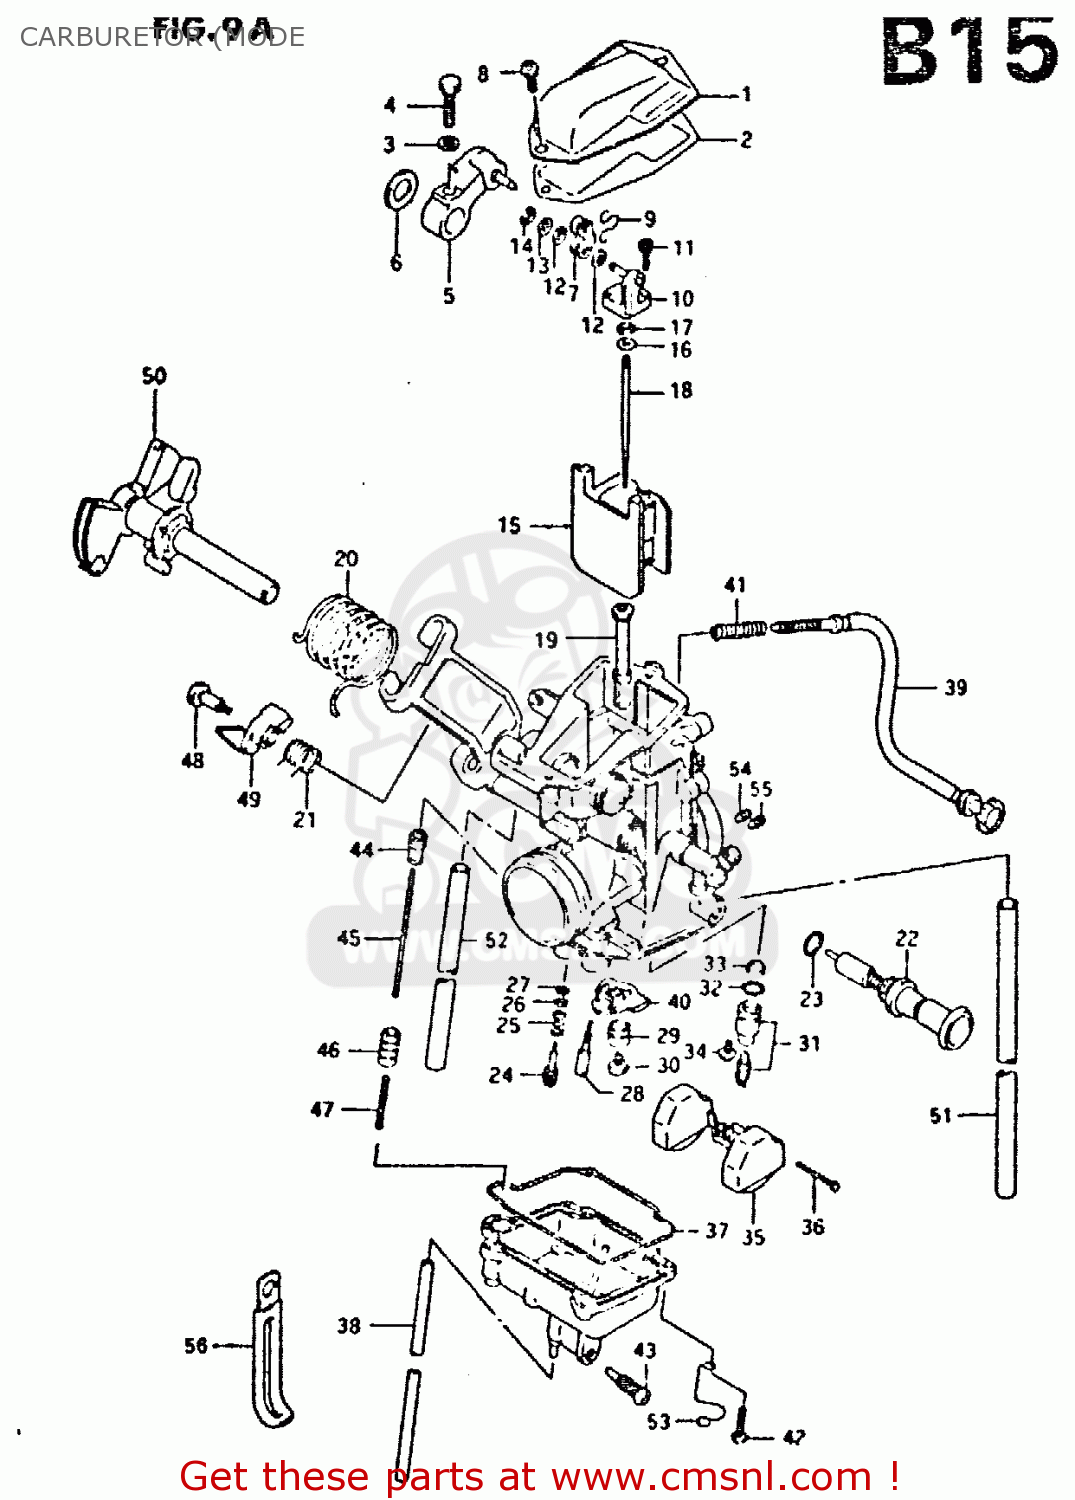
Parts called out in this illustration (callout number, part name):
1	COVER,CARBURETOR,TOP
2	GASKET,CARBURETOR TOP (NAS)
3	LOCK,WASHER
4	BOLT
5	ARM,THROTTLE
6	RING,THROTTLE SHAFT
7	PLATE
8	SCREW
9	SPRING
10	CONNECTOR
11	SCREW
12	GASKET (NAS)
13	WASHER
14	E-RING
15	VALVE,PISTON
16	WASHER,JET NEEDLE
17	CLIP
18	NEEDLE,JET
19	JET,NEEDLE(P-8)
20	SPRING
21	SPRING
22	PLUNGER ASSY
23	O RING
24	SCREW,PILOT
25	SPRING
26	WASHER
27	O RING,PILOT AIR SCREW
28	JET,PILOT(37.5)
29	RING,MAIN JET FIXING
30	JET,MAIN(127.5)
31	VALVE ASSY, NEEDLE
32	O-RING,NEEDLE VALVE
33	FILTER
34	SCREW
35	FLOAT
36	PIN,FLOAT
37	O RING,FLOAT CHAMBER
38	HOSE(3X5X600)
39	ADJUSTER ASSY
40	RING
41	SPRING
42	SCREW
43	SCREW,DRAIN
44	BOOT, ACCELE PUMP ROD
45	ROD
46	PLUNGER
47	SPRING
48	BOLT
49	LEVER
50	SHAFT ASSEMBLY
51	HOSE(5X9X600)
52	HOSE(5X9X600)
53	CLIP
54	JET,MAIN AIR(0.7)
55	JET,AIR(1.1)
56	CLAMP(L:45)
57	CLAMP
